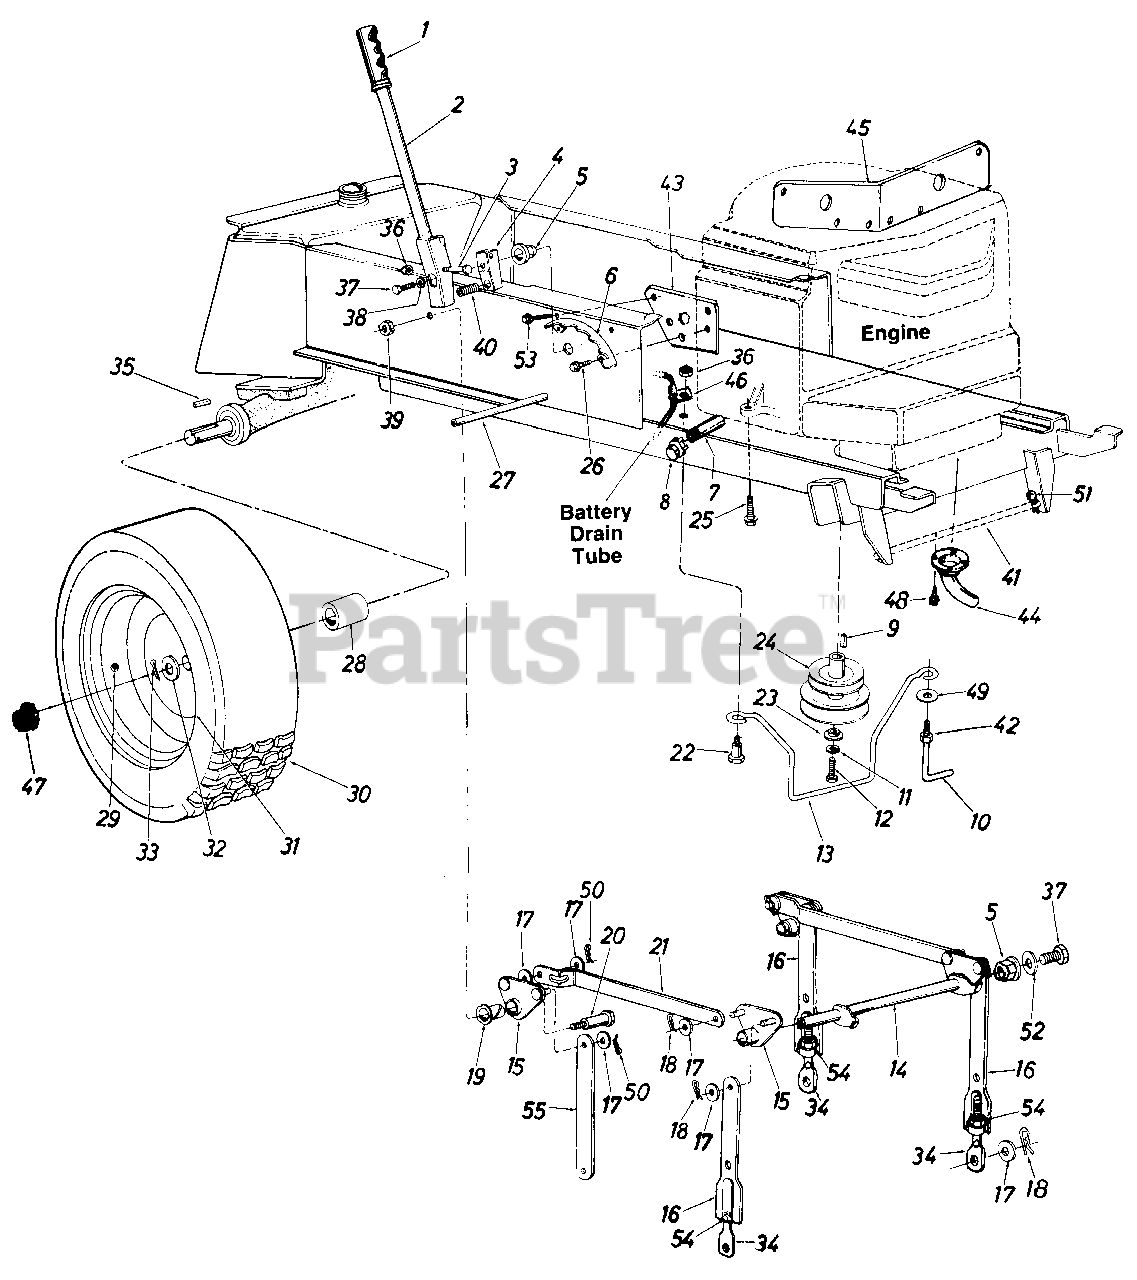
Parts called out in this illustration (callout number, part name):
2	Lift Handle Ass'y.
3	Hex Bolt 5/16-18 x 1.5" Lg.
4	Lift Shaft Drive
5	Plastic Hex Brg. 5/8" I.D.
6	Index Brkt. Deck Lift
7	Pipe Nipple 3/8-18 Npt.
8	Pipe Cap 3/8-18 Npt.
9	Sq. Key 1/4" x 1/4" x 1.50" Lg.
10	Belt Guard Lock Pin
11	L-Wash 7/16" I.D.
12	Hex Scr. 7/16-20 x 1.50" Lg.
13	Belt Guard
14	Lift Shaft Ass'y.
15	Lift Pivot Brkt. Ass'y.
16	Adj. Deck Lift Link
17	Fl-Wash. 1/2" I.D. x 1.00" O.D. x .090
18	Hairpin Cotter
19	Nyliner 5/8" I.D. x .88" Lg.
20	Shld. Bolt 5/8" Dia. x .96" Lg. 3/8-16
21	Connecting Link
22	Shld. Bolt .437 Dia. x .268 Lg. 5/16-18
23	Flat Wash. .44" I.D. x 1.25" O.D. x .17
24	Two-Step Engine Pulley 4.75" & 5.56
25	Hex Wash. Hd. Scr. 3/8-16 x 1.25" Lg.
26	Hex Thd. Rolling Scr. 5/16-24 x.50" Lg.
27	Running Board Rod
28	Spacer 1.0" I.D. x 1.25" O.D. x 2.12" Lg.
29	Air Valve
33	Cotter Pin 3/16" Dia. x 1.50" Lg.
34	Eye Bolt Adj. Link 1/2-13 Thd.
35	Sq. Key 1/4 x 3.0"
36	Hex Cent. L-Nut 5/16-18 Thd.
37	Hex Scr. 5/16-24 x .62" Lg.'
38	L-Wash. 5/16" I.D.
39	Hex Top L-Nut 3/8-16 Thd.
40	Compression Spring
41	Deck Connecting Rod
42	Hex Nut 5/16-24 Thd.
43	Index Brkt. Reinforcement Plate
44	Exhaust Pipe
45	Heat Shield
46	Mounting Clamp
47	Hub Cap
48	Hex Wash. Hd. AB-Tap Scr. #10 x .50" Lg.
49	Bell-Wash. .39" I.D.
50	Cotter Pin .09 Dia. x 1.0" Lg.
51	Int. Cotter Pin
52	Flat Wash. .34" I.D. x 1.12" O.D. x .125
53	Hex Wash. Hd. AB-Tap Scr. 5/16 x .62" Lg.
54	Hex Nut 1/2-13 Thd.
55	Deck Link
